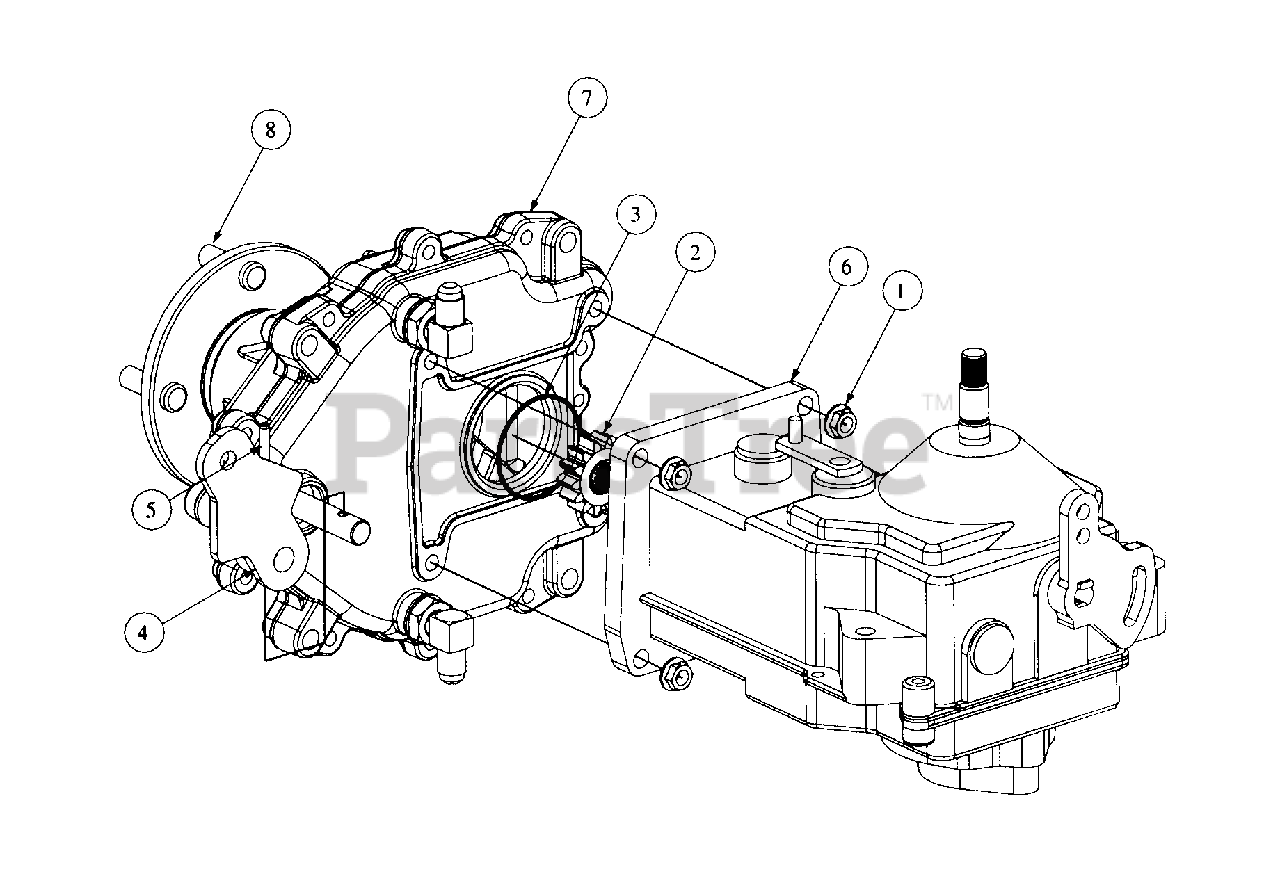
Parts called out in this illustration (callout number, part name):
1	Lock Nut, Hex Flange 5/16-18
2	Gear, Spur, 14T
3	O-Ring, 2.00 x .070
4	Lever, Brake, Park
5	Pin, Spirol, 3/16 x 1.25 HD
6	Pump Kit, Hydro, Left Hand
7	Transmission Assembly
8	Rib Neck Studs, 7/16-14 X 1.6
